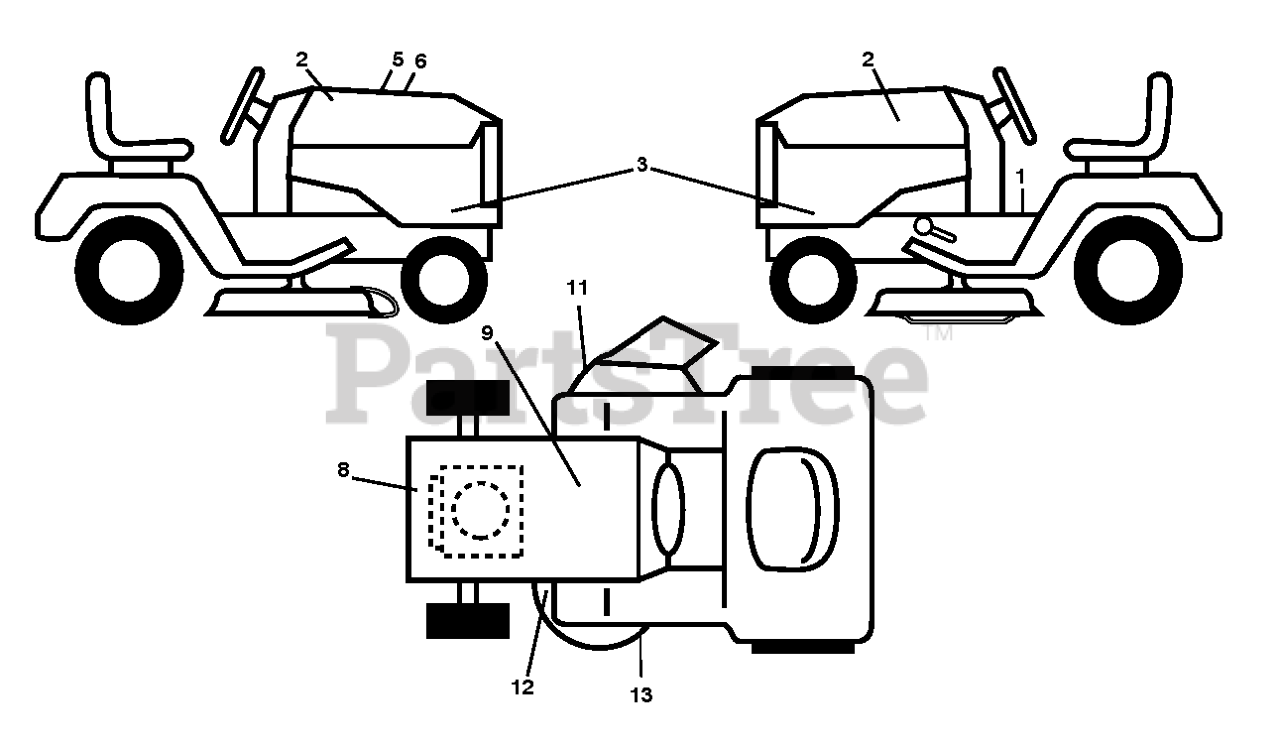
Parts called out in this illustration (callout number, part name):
1	DECAL.FENDER.WARNING.ENG
2	RP.DECAL.BADGE.170MM.TEXTLOGO
3	DECAL, PANEL SIDE
5	DECAL.WARNING.CUST.RESP.E85.
6	Decal, Replacement
8	DECAL.ENG.BS.23HP.XRD.TWIN
9	DECAL BTRY SYMBOLS
11	DECAL.WARN.KEEP.HAND.AWAY
12	DECAL.MOWER
13	DECAL.MOWER.SCH.48/54
